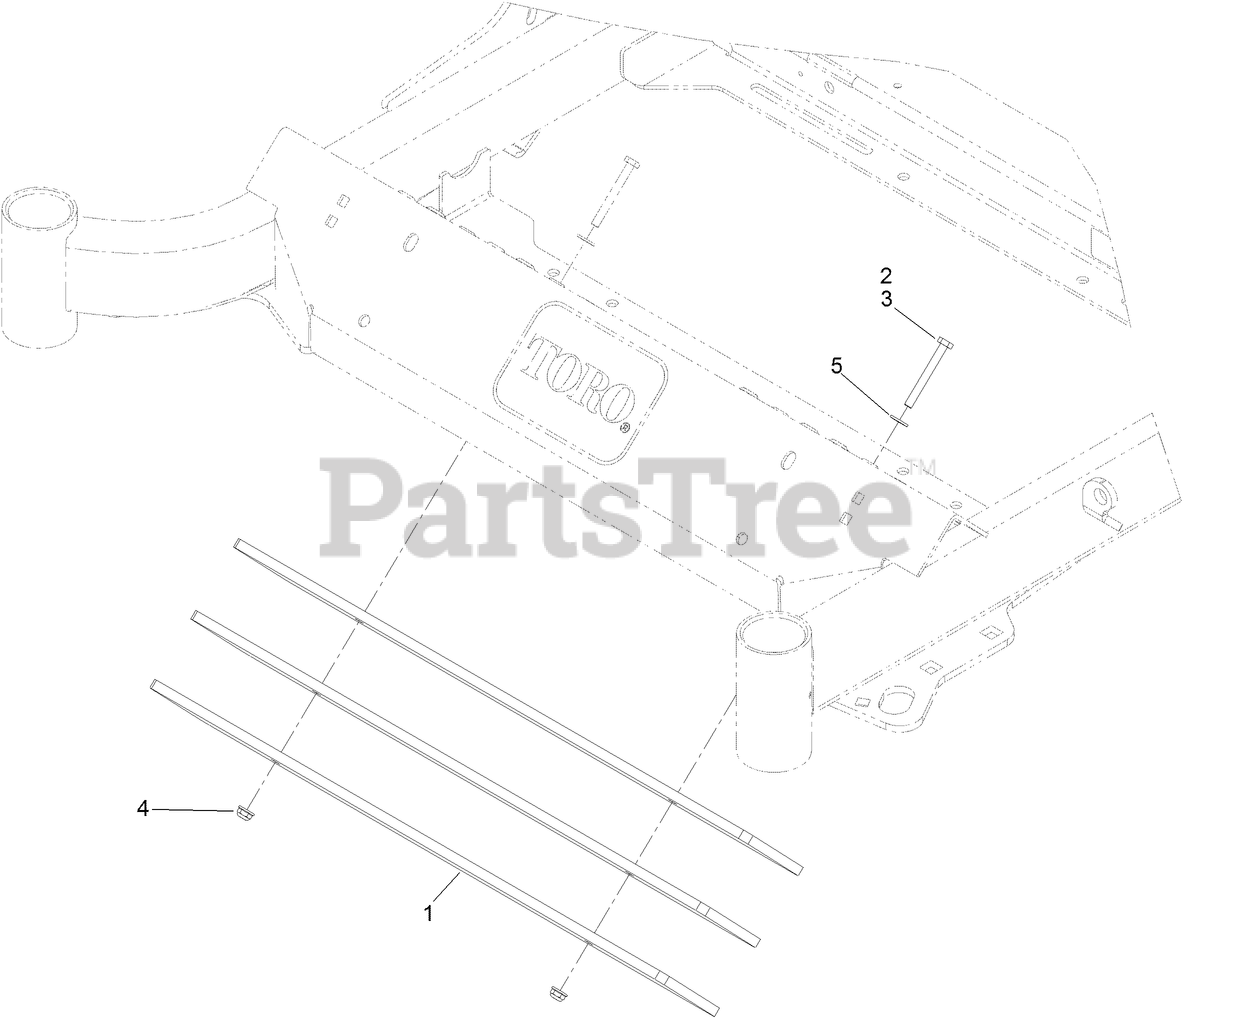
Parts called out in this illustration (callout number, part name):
2	SCREW-HH
3	SCREW-HH
4	NUT-HF
5	WASHER-FLAT
